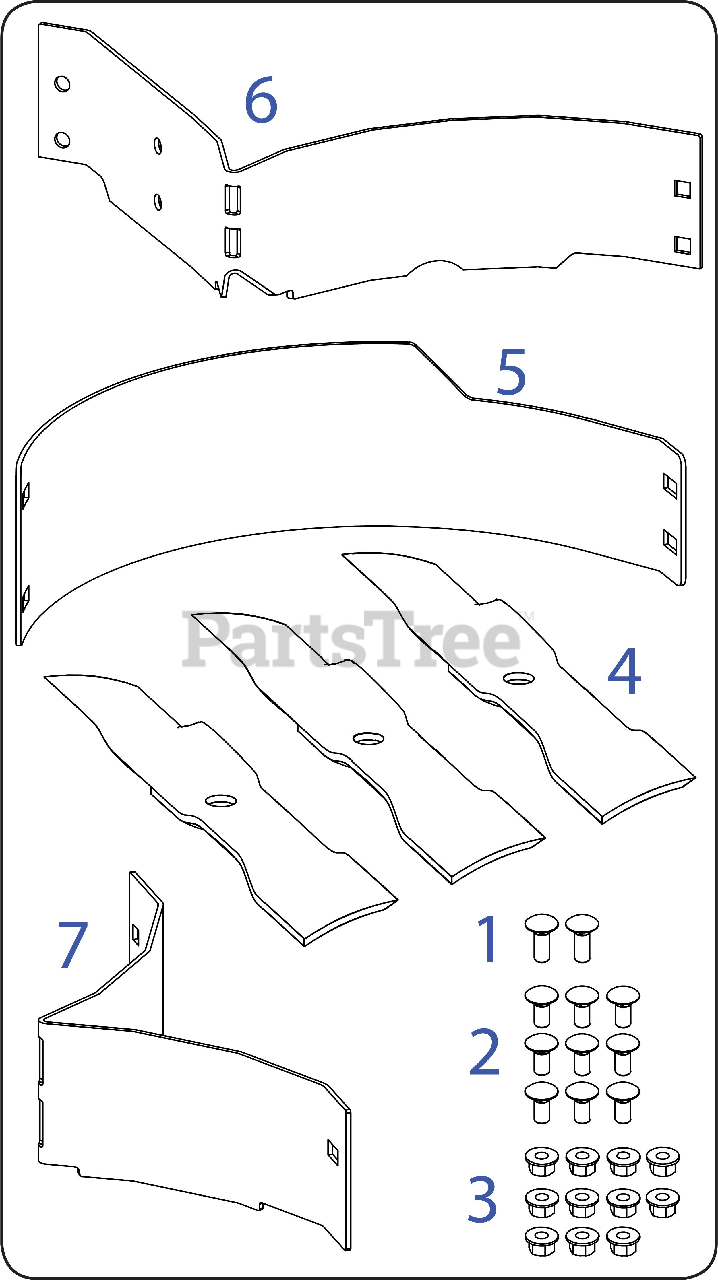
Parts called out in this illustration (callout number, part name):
1	Carriage Bolt 3/8-16 X 1.00 Gr5
2	Carriage Bolt 3/8-16 X .75
3	Nut-Ctrlck Flg Hex
4	Blade-21"Mulch 60"
5	60" Discharge Baffle
6	Mulch Baffle (Center)
7	Mulch Baffle (Left)
